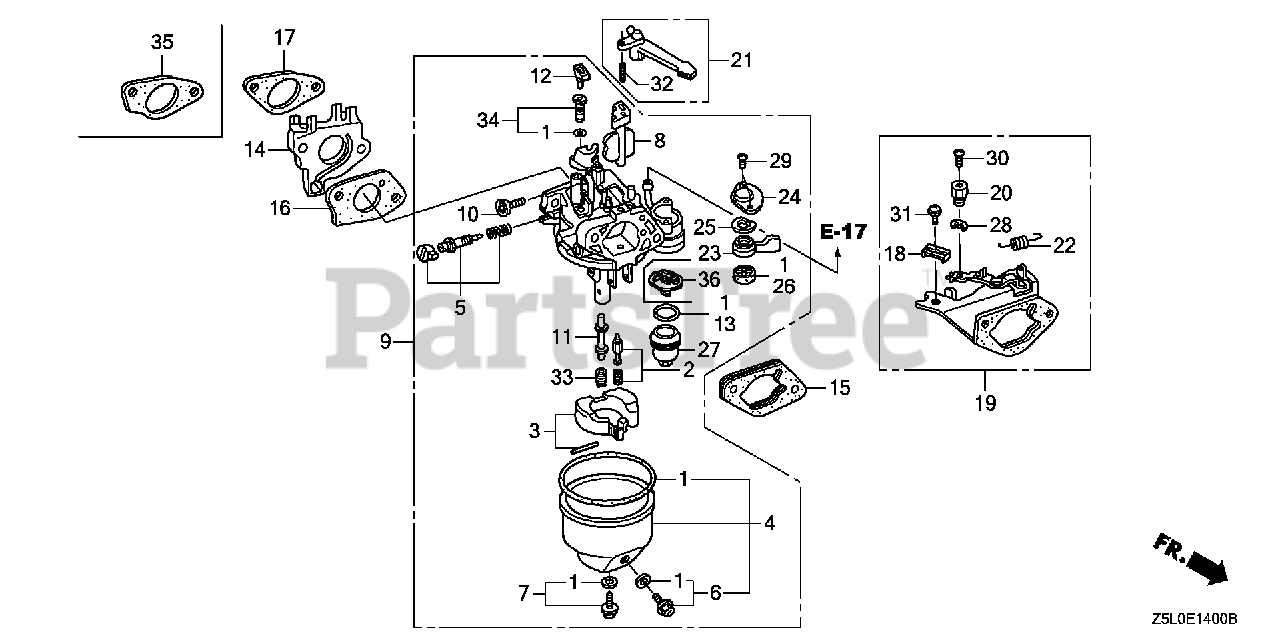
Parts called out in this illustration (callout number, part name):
1	GASKET SET (INCLUDE 16173-001-004) (INCLUDES 16173-001-004)
2	VALVE SET, FLOAT
3	FLOAT SET
4	CHAMBER SET, FLOAT
5	SCREW SET (Honda Code 4219879). (CARBURETOR NO.)
6	SCREW SET, DRAIN
7	SCREW SET (CARBURETOR NO.)
8	CHOKE SET
9	CARBURETOR ASSY. (BE80M A)
10	SCREW, THROTTLE STOP
11	NOZZLE, MAIN
12	COLLAR, SET
13	GASKET, FUEL STRAINER CUP
14	INSULATOR, CARBURETOR
15	SPACER, CARBURETOR
16	GASKET, CARBURETOR
21	LEVER, CHOKE (STD)
23	LEVER, VALVE
24	PLATE, LEVER SETTING (CARBURETOR NO.)
25	SPRING, PETCOCK LEVER (CARBURETOR NO.)
26	GASKET, VALVE
27	CUP, FUEL STRAINER
29	SCREW, PAN (3X6)
32	PIN, SPRING (2X12)
33	JET, MAIN (#90) Use from Engine SN BE81B C.
33	JET, MAIN (#95)
33	JET, MAIN (#98) Use from Engine SN BE87A A to BE87A A.
34	JET SET, PILOT (#38)
35	GASKET, CARBURETOR INSULATOR
36	FILTER, CUP (CARBURETOR NO.)
